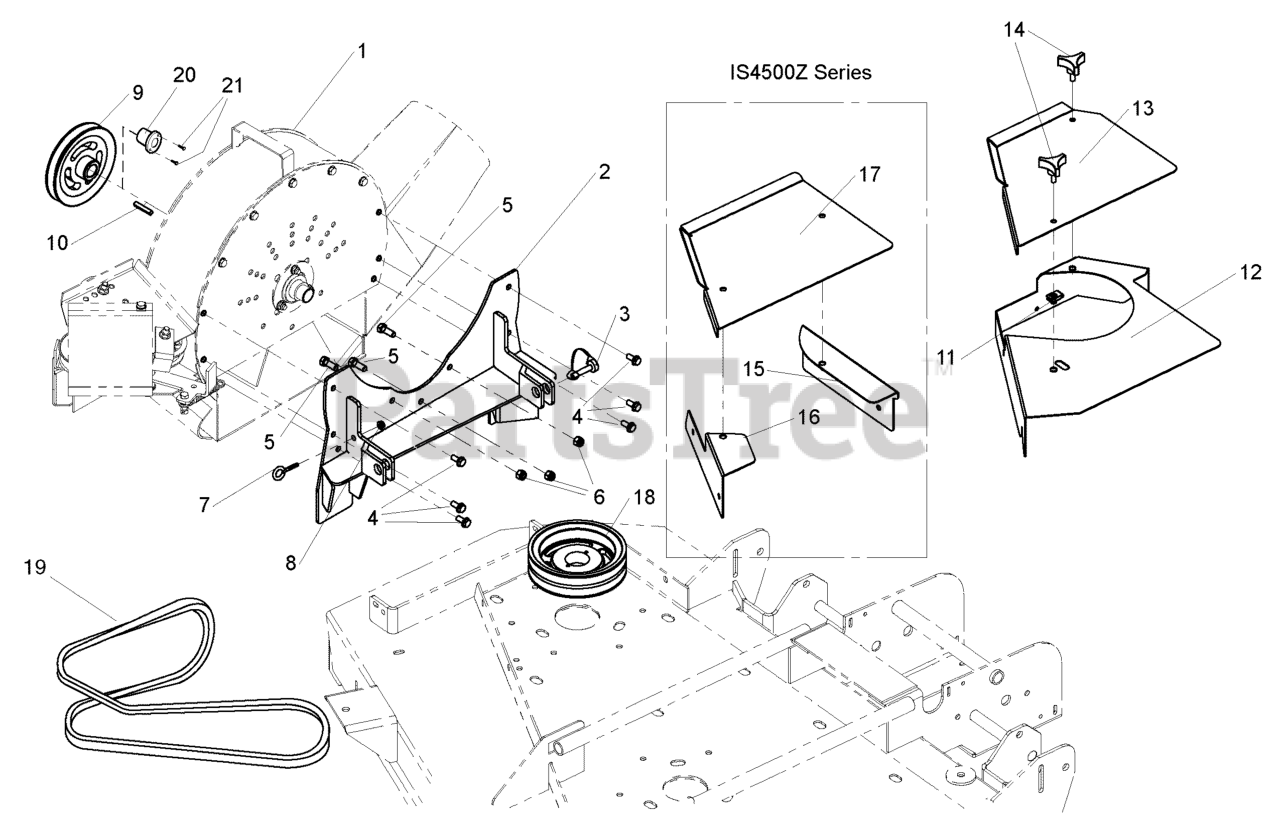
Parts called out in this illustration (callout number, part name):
1	BLOWER ASSEMBLY
2	WELD, BLOWER MOUNT, 61" - BLK
3	SNAPPERPIN, 5/16 X 2
4	BOLT, 5/16-18 X 3/4" SELF LOCK
5	BOLT, 3/8-16 X 1" GD5 CZ
6	NUT, 3/8-16 HEX NYLON LOCK
7	EYE BOLT, 1/4-20 X 2.5, 1THRD, .5EYE,CZ
8	NUT, 1/4-20 HEX NYLOCK FLANGE
9	PULLEY
9	PULLEY, BH72
10	KEY 1/4 SQ X 1-1/2 LONG
11	BODY CLIP, 5/16-18-7GA MATERIAL
12	WELD, GUARD DECK
13	BELT SHIELD, 61" BLOWER DECK
14	KNOB, PLASTIC, 5/16-18 X 3/4"
15	WELD, GUARD DECK, BACK
16	WELD, GUARD DECK, FRONT
17	BELT SHIELD, 61" BLOWER DECK
18	PULLEY
18	PULLEY, DH4780
19	BELT, #7-8764
19	BELT, 48X1030, 1/2 X 103", PREM CONST.
20	BUSHING, TAPERED HUB
21	BOLT, 1/4-20 X 1" GD5 CZ
